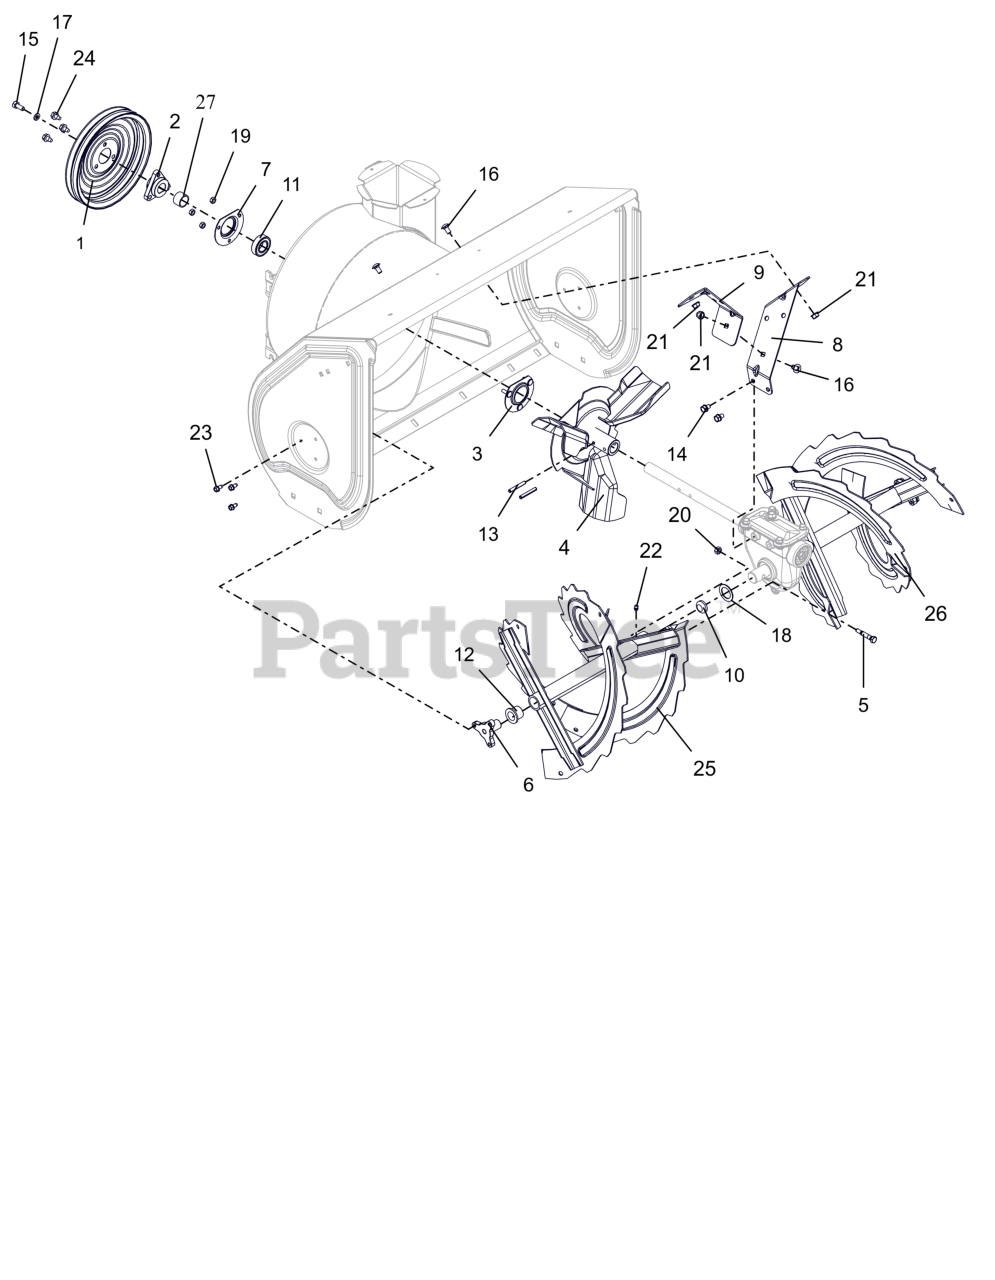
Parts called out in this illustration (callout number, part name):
1	PULLEY, SPIN FORM DUAL GROOVE
2	PULLEY HUB, D-BORE .87 DELUXE
3	BEARING FLANGE
4	IMPELLER, 3 BLADE-14"
5	SHEAR BOLT SERVICE ASSEMBLY
6	SUPPORT, RAKE BUSHING
7	BEARING FLANGE
8	BRACKET, GEARCASE SUPPORT - LH
9	BRACKET, GEARCASE SUPPORT - RH
10	PLUG, RAKE TUBE
11	BRG-BALL .876 X 1.750 X .50
12	BSHG-FLG, NY.778 ID X 1.018 OD
13	PIN-ROLL .250X1.75
14	BLT, SEMS .31-18X.50 G5 ZCC
15	BLT, HEX .31-24X.750 G5 ZCC
16	BLT,RHSSN.31-18X.625 G5 ZCCP30
17	WSHR, LK-HVY .312X.097 ZCC
18	WSHR, FLT 1.010X1.505X.062 ZCC
19	NUT,LK-CTR .25-20 GA ZCC
20	NUT,LK-CTR .31-18 GA ZCC
21	NUT-LK-TOP-FLG .312-18 GF ZCC
22	ZERK,FITTING .25X.125 DRIVE IN
23	SCR-TAP .25-20X.50 HWH ZCC
24	SCR,TAP .312-18X.50 HWH TR ZCC
25	RAKE, RH W/ZERK - 30"
26	RAKE, LH W/ZERK - 30"
27	BSHG,SPCR .895X1.065X.693
